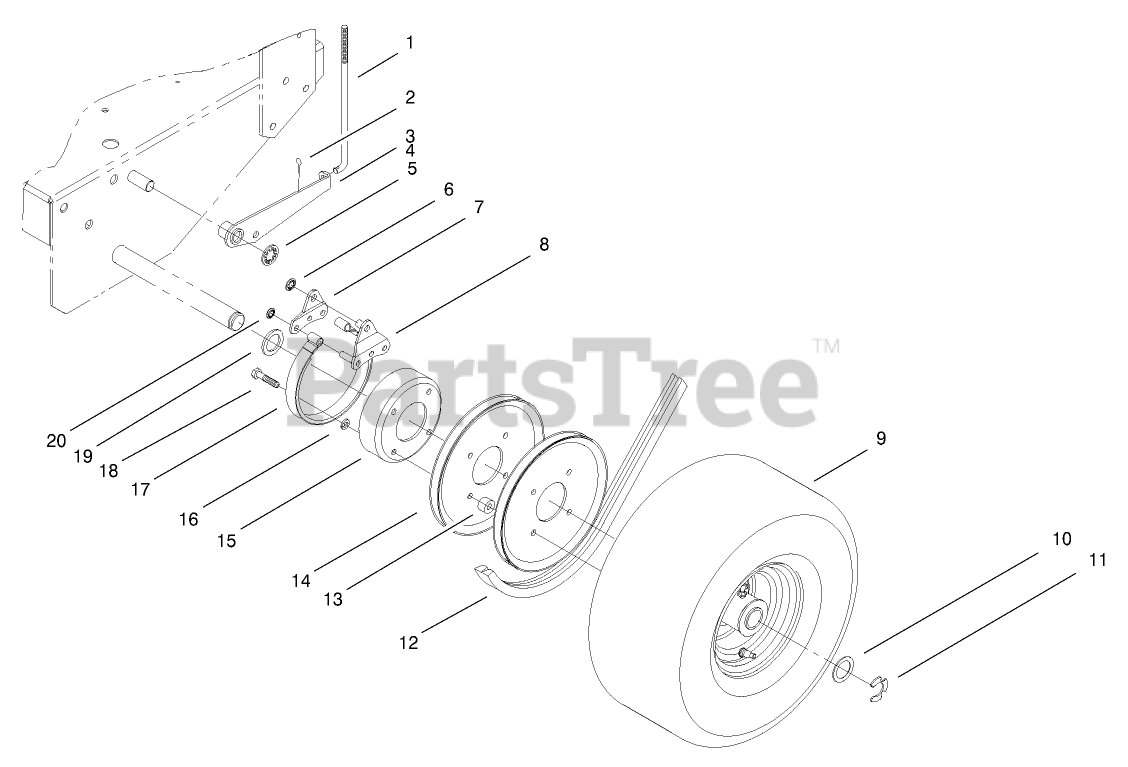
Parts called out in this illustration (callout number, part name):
1	ROD-BRAKE
2	PIN-COTTER
3	ARM-BRAKE, RH
4	ARM-BRAKE, LH
5	RING-RETAINING
6	RING-RETAINING, EXTERNAL
7	PLATE-LINK, BRAKE
8	LINK-BRAKE
9	WHEEL AND TIRE ASM
10	WASHER-THRUST
11	RING-RETAINING
12	V-BELT
13	SPACER-PULLEY
14	PULLEY-WHEEL
15	DRUM-BRAKE
16	WASHER-LOCK
17	BAND-BRAKE
18	SCREW-HH
19	WASHER-WHEEL
20	RING-RETAINING
